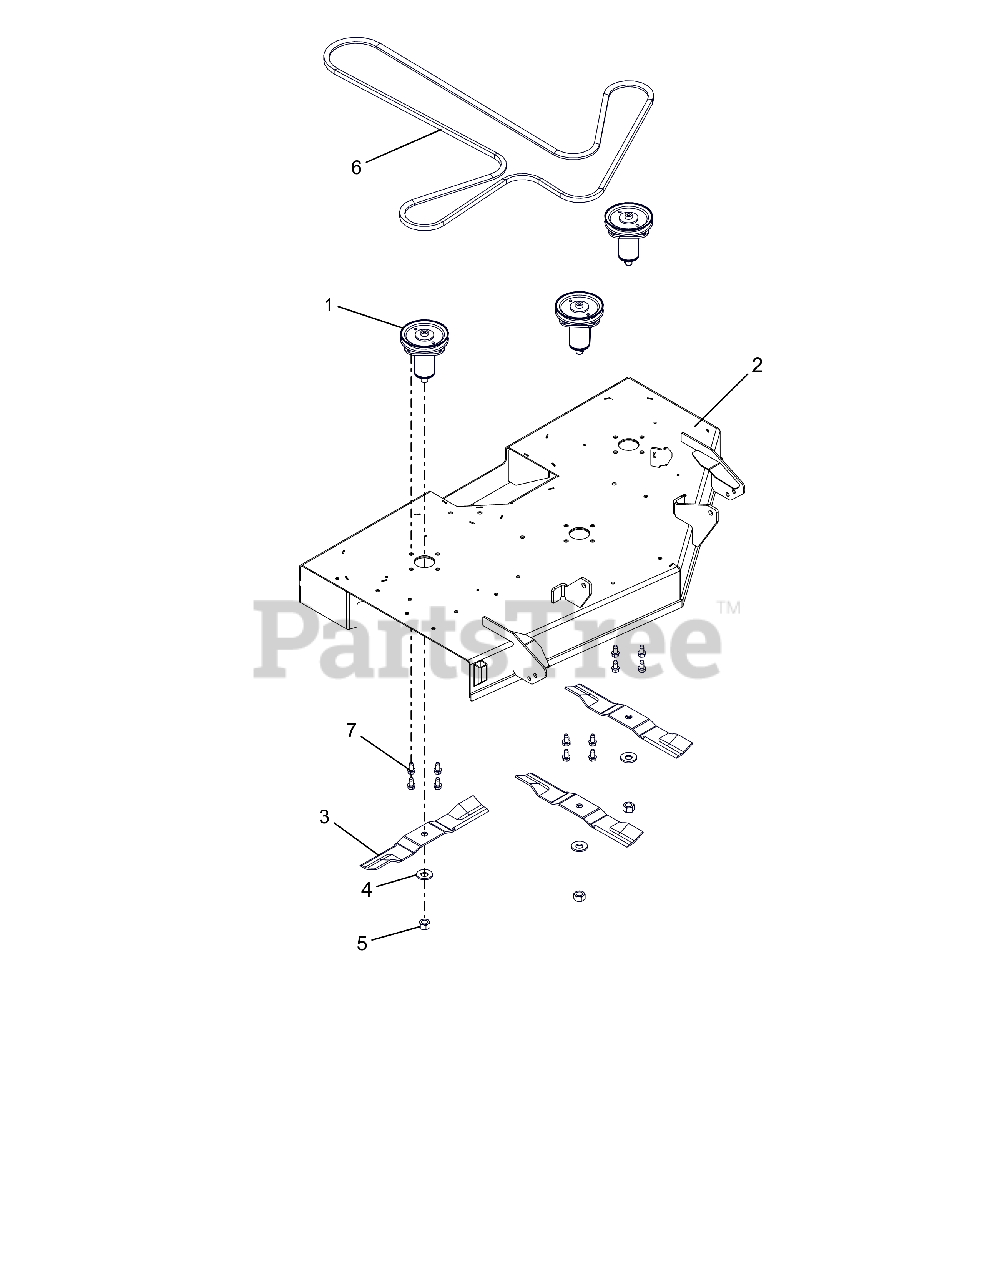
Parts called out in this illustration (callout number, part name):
1	KIT, DECK SPINDLE ASM-IKON-ZTX
2	KIT, 42" ARIENS DECK W/DECALS
3	BLADE, MOWER 15.00"
4	WSHR-BLVL .669X1.535X.138
5	NUT-STD .625-18 ZCC
6	V-BELT, 4L-WRAPPED
7	SCR,TAP .375-16X.75 HWH TR ZCC
